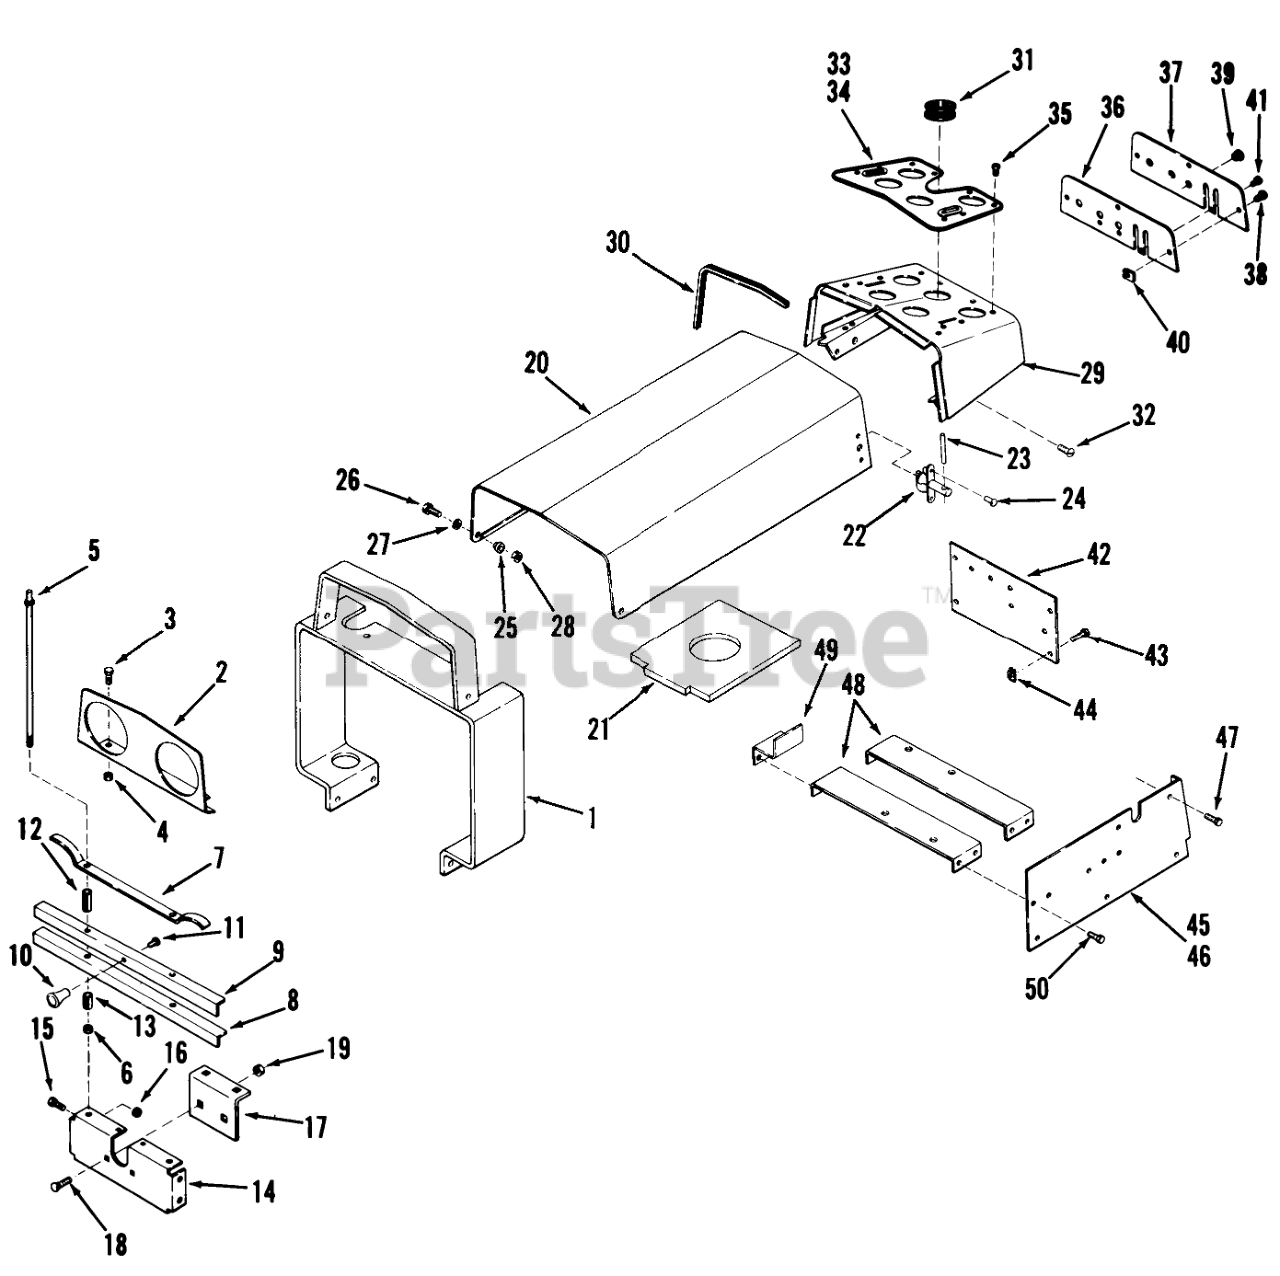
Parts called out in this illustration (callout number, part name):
1	Asy-Grille Shroud
2	Light Bracket
3	HHCS
3	Bolt
4	Nut
5	ROD-GRILLE
6	Nut
7	SPRING GRILLE
8	ANGLE-GRILLE
9	ANGLE-GRILLE
11	SCREW
12	Spacer
13	Spacer
14	Cover-Front
15	Bolt
16	NUT
17	Cover
18	Bolt-Hex
19	Nut
20	Assy-Hood
21	INSULATION FOAM
22	Latch
24	RIVET
25	Bushing
26	HHCS
27	WASHER 5/16 SAE
28	Nut
29	Control Housing
30	Edge Trim
31	GROMMET
32	SCREW
33	Plate-Instrument
34	Plate-Instrument
35	Plate Screws
36	Plate
37	Plate-Rear Instrument
38	Screw
39	PLUG BUTTON
40	Speed Nut
41	Plate Screws
42	Panel
43	Screw
45	Panel-Console RH
46	Panel-Console LH
47	SCREW
48	Battery Support
49	Battery Bracket
50	SCREW
